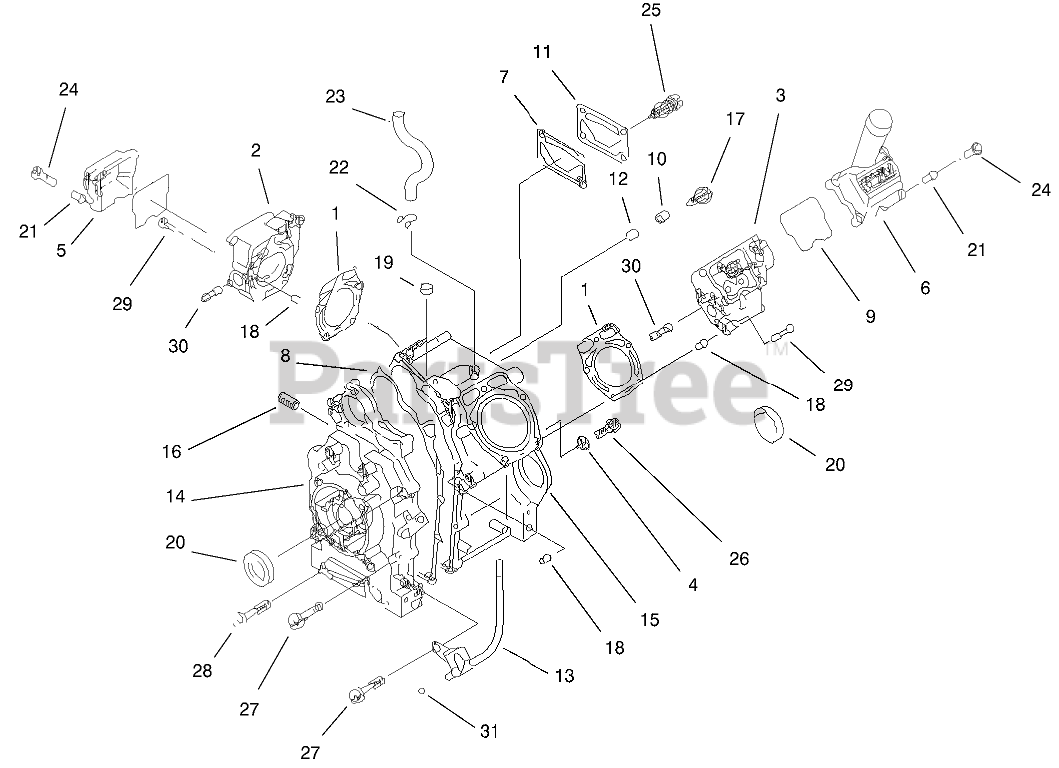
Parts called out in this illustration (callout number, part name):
1	GASKET HEAD
2	HEAD COMP CYL
3	HEAD COMP CYL
4	GASKET
5	CASE-ROCKER
6	CASE-ROCKER
7	GASKET
8	GASKET-CRANKCASE COVER
9	GASKET-ROCKERCASE
10	PLATE
11	COVER
12	VALVE
13	PIPE - OIL LEVEL
14	COVER-CRANKCASE
15	Crankcase-Comp
16	JOINT
17	SCREW
19	SEAL-OIL, VC (6X10X2.5)
20	SEAL-OIL
21	COLLAR
22	CLAMP
24	BOLT-FLANGED (6X25)
25	BOLT-FLANGED
26	BOLT-FLANGED
27	BOLT-FLANGED
28	BOLT-FLANGED
29	BOLT-FLANGED
30	BOLT-STUD
31	O-RING
